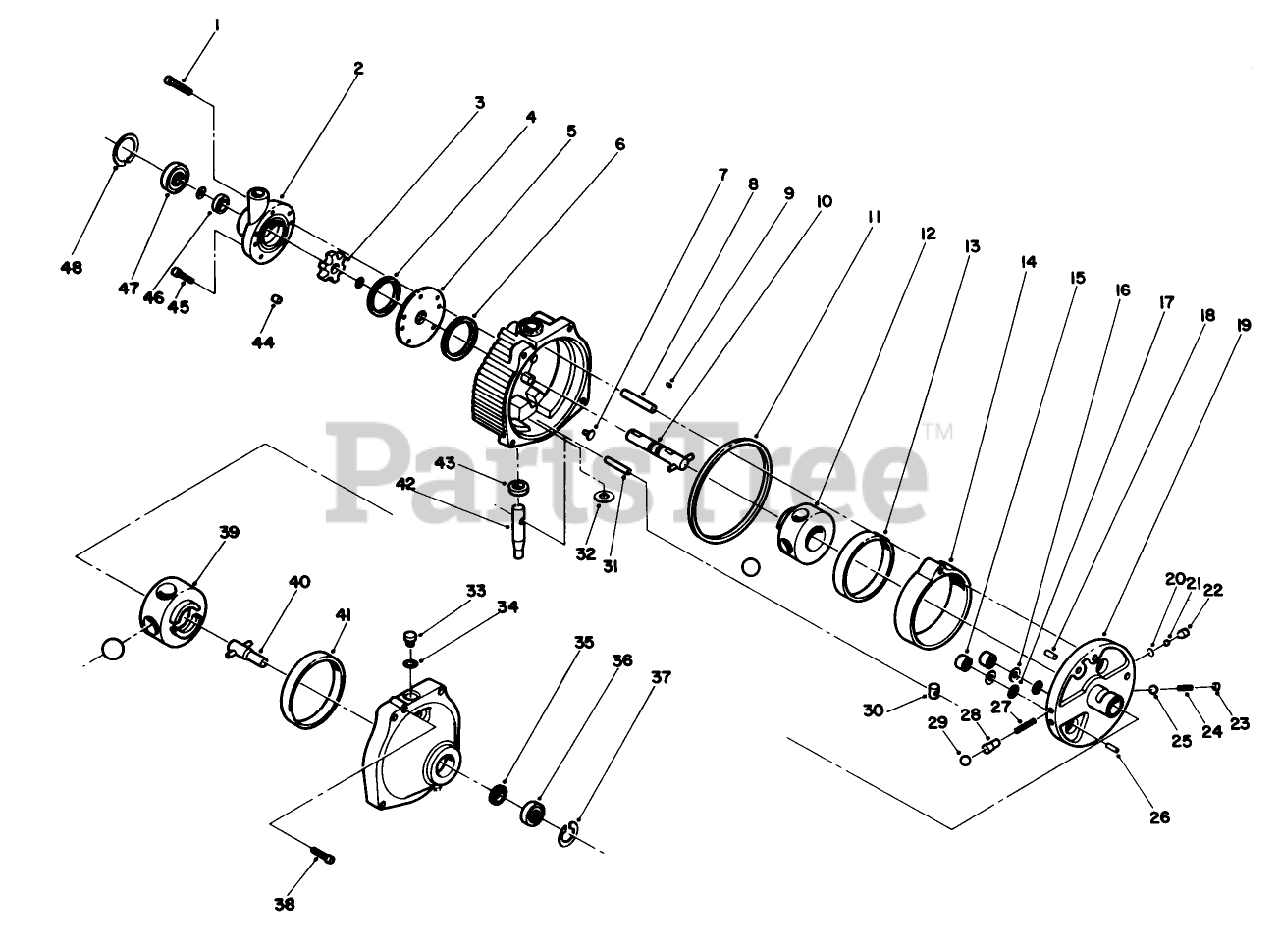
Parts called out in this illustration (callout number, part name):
1	CAPSCREW
2	CHARGE PUMP
3	CARRIER
5	PLATE
7	BUTTON
9	Drive Pin
10	SHAFT
12	ROTOR
13	Pump Race
14	Cam Ring Assy. (Incl. Ref. #13)
15	PISTON
17	O-RING
19	Pintle Assembly (Incl. Ref. #15-18,20,22-26,27-29)
24	SPRING
27	SPRING
30	INSERT
31	Dowel
32	Control Shaft Washer
33	"O" Ring Plug Sub-Assembly (Incl. Ref. #34)
34	O-RING
35	Oil Seal
36	Bearing
38	Socket Head Capscrew
39	ROTOR
40	SHAFT
42	SHAFT KIT
43	SEAL-OIL
45	SCREW-HH
46	SEAL-OIL
47	BEARING
48	RING
